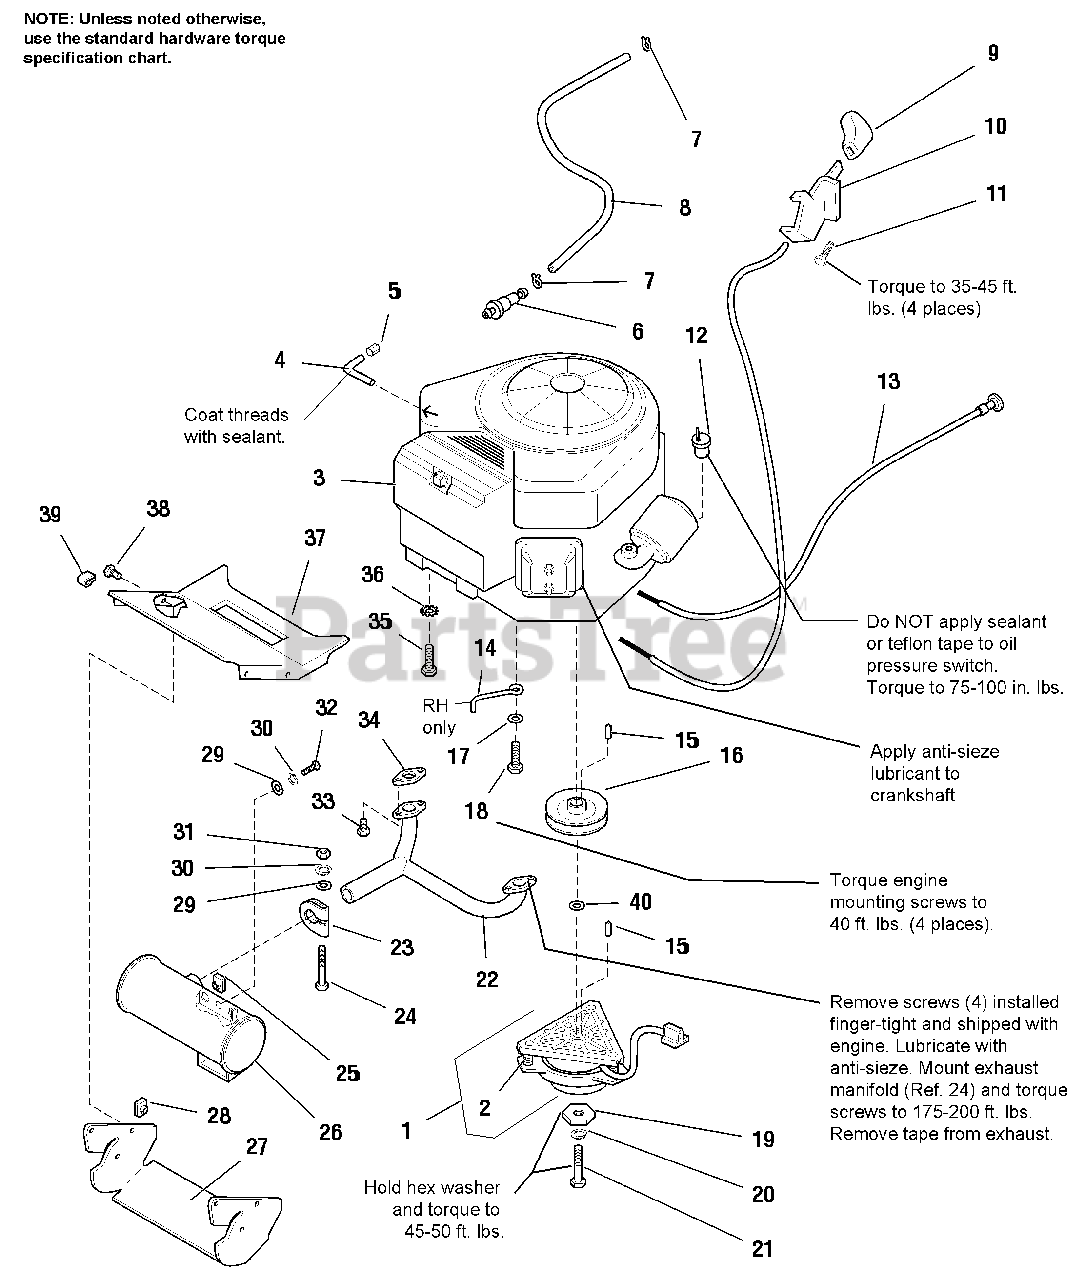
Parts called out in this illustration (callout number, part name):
1	ELECTRIC CLUTCH
2	SPRING & NUT KIT
3	ENGINE, 14HP, 16HP or 18HP Briggs & Stratton V-Twin Vanguard
4	DRAIN PIPE, Oil
6	FUEL FILTER
7	CLAMP, Hose
8	HOSE, Fuel, 45-1/2" Long
9	KNOB, Throttle
10	THROTTLE CONTROL ASSY.
11	CAPSCREW, Hex Washer Hd, Plastite, 1/4-20 x 1/2
12	SWITCH, Oil Pressure
13	CABLE, Choke Control
15	KEY, Hi-Pro
16	PULLEY ASSY.
17	WASHER, Plain, 13/32
18	CAPSCREW, Taptite, 3/8-16 x 1-1/2
19	WASHER, Hex
20	LOCKWASHER, 7/16
21	CAPSCREW, 7/16-20 x 2-1/2
22	MANIFOLD, Exhaust
23	CLAMP, Muffler
24	CARRIAGE BOLT, 5/16-18 x 2-3/4
25	PAL NUT, 5/16-18
26	MUFFLER ASSY.
27	DUCT, Lower Muffler
28	PAL NUT, 1/4-20
29	WASHER, 5/16
30	LOCKWASHER, 5/16
31	NUT, Hex, 5/16-18
32	CAPSCREW, Hex Hd, 5/16-18 x 1
33	CAPSCREW, Metric
34	GASKET, Exhaust Manifold
35	CAPSCREW, Taptite, 3/8-16 x 1-1/2
36	LOCKWASHER, External Tooth
37	DUCT, Upper Muffler
38	CAPSCREW, Hex Flange Hd, Whizlock, 1/4-20 x 5/8
39	CLIP
40	WASHER
